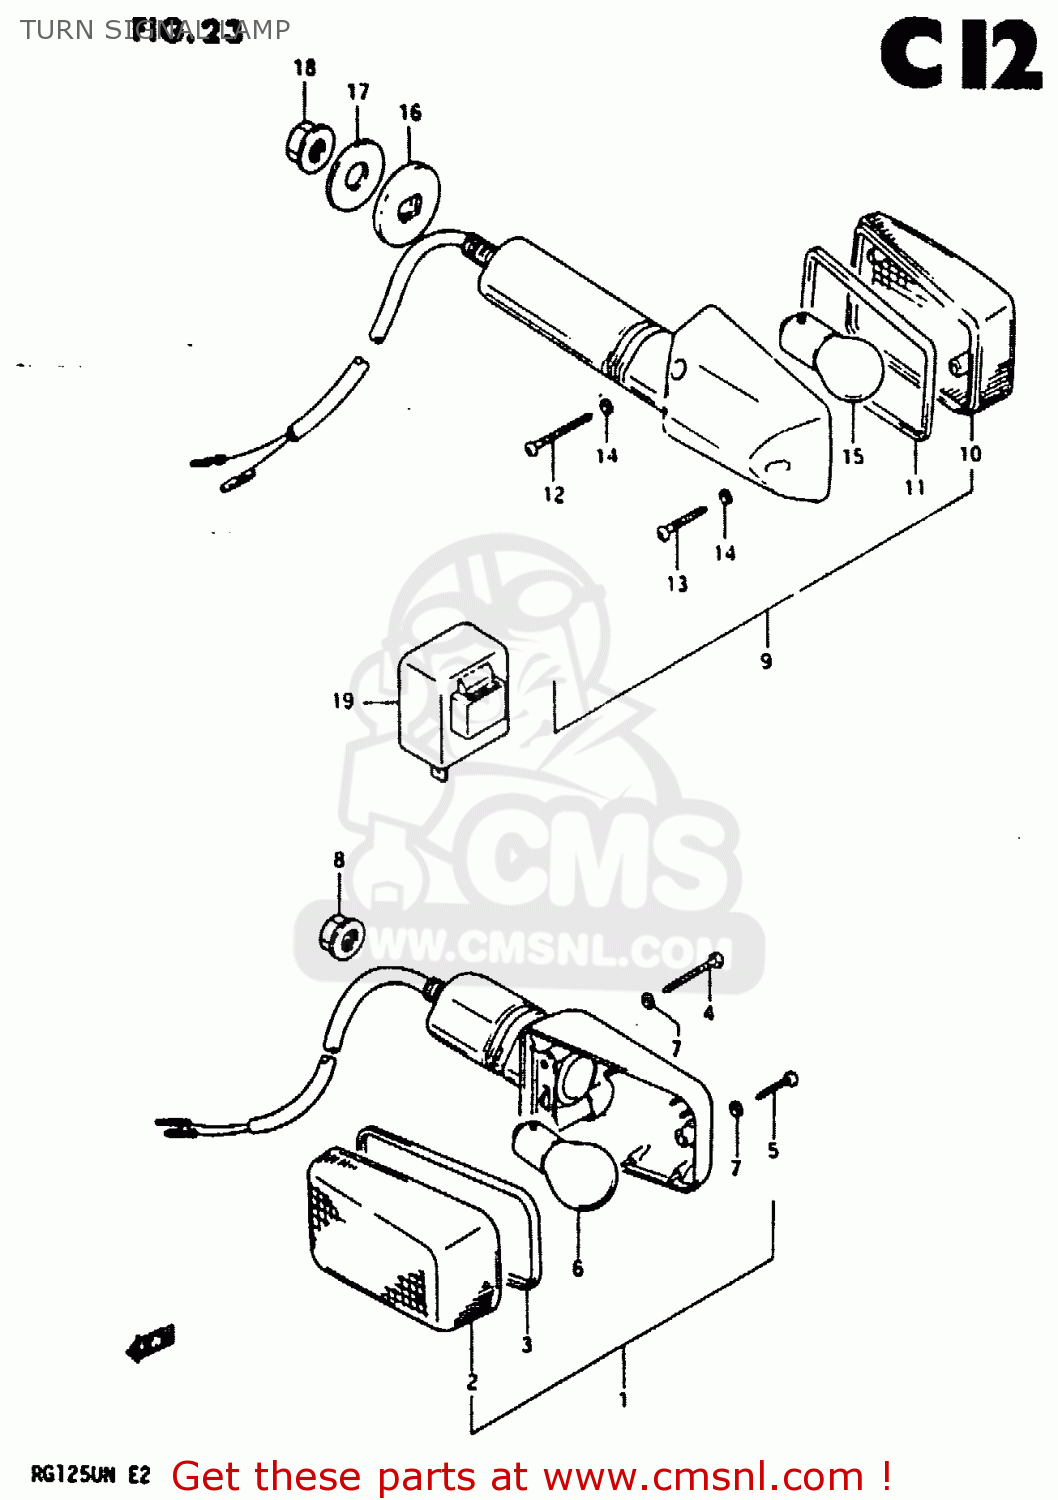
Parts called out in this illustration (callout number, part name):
1	LAMP ASSY,FR TURN SIGNAL
2	LENS
3	GASKET (NAS)
4	SCREW(3X30)
5	SCREW
6	BULB(12V21W)
7	GASKET (NAS)
8	NUT
9	LAMP ASSY,RR TURNSIGNAL
10	LENS
11	GASKET (NAS)
12	SCREW(3X30)
13	SCREW
14	GASKET (NAS)
15	BULB(12V21W)
16	SPACER,RR TURNSIGNAL
17	WASHER(10.5X30X3.2)
18	NUT
19	RELAY ASSEMBLY,TURN SIGNAL
